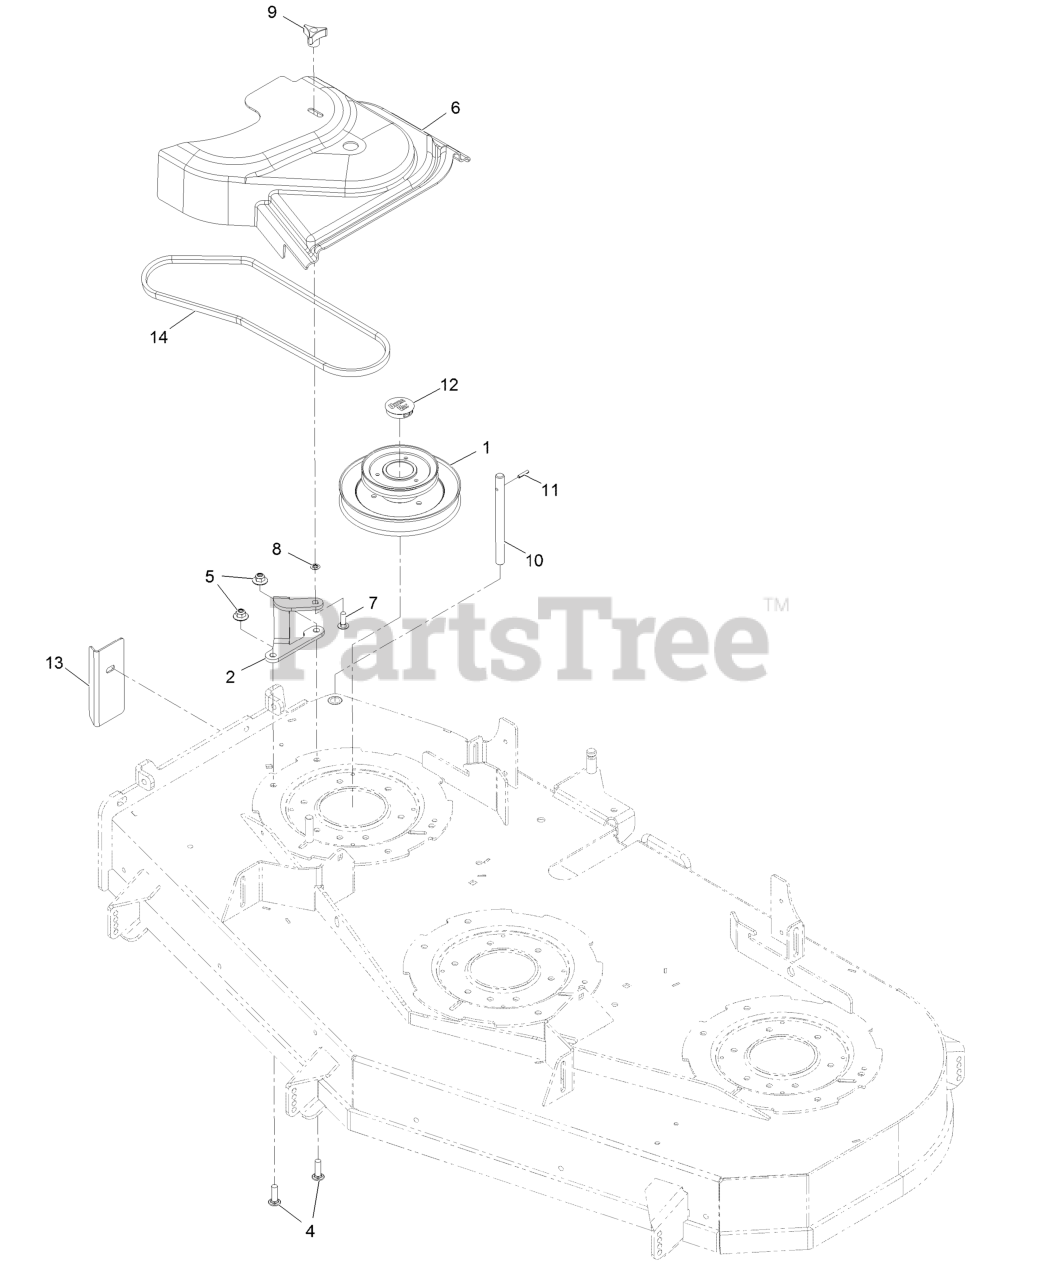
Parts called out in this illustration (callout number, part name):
1	JACKSHAFT,UV DRIVE 604 SPLINED
2	BRACKET,BELT COVER
4	Bolt-Carriage 3/8-16 X 1 1/4
5	Nut-Nyloc 3/8-16 Flg
6	COVER-BELT UVE 60
7	BOLT-CARR
8	RING-RETAINING, BOLT
9	KNOB-3 PRONG
10	SHAFT-CATCHER, GRASS
11	PIN-ROLL
12	PLUG, BLACK NYLON 1.75
13	PLATE-BLOCKER
14	BELT- 4L SECTION
